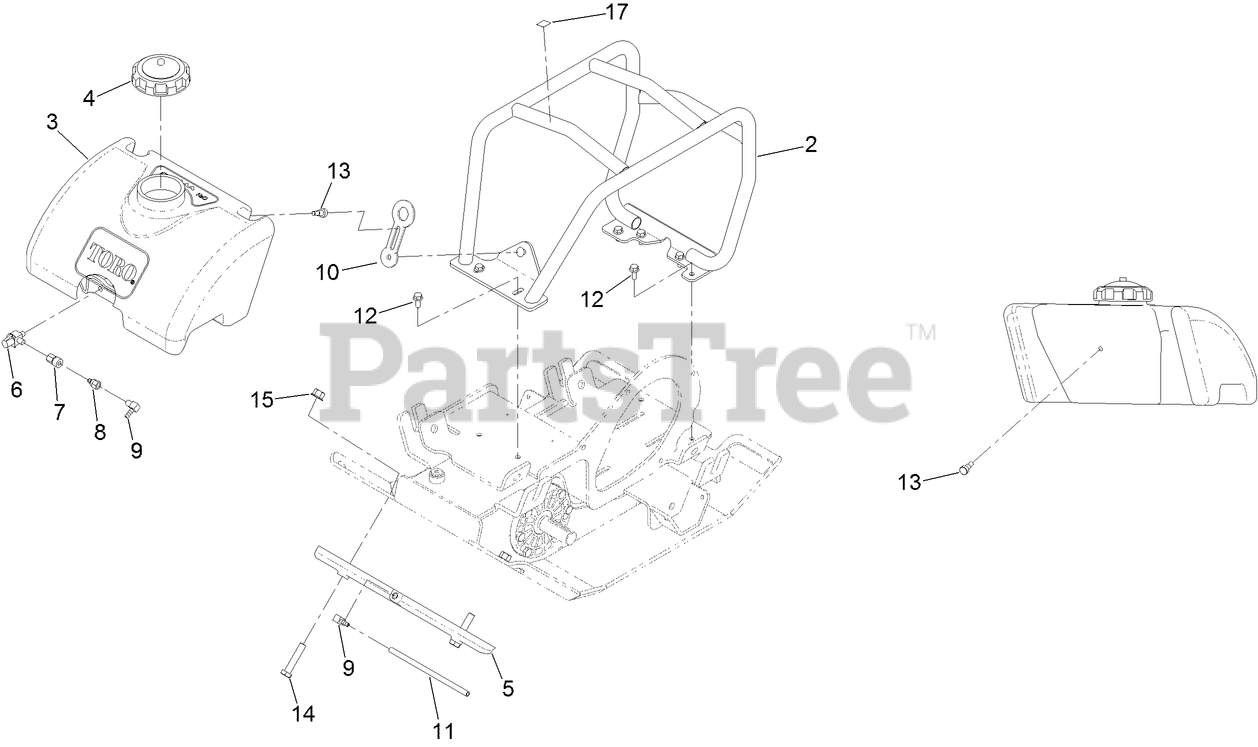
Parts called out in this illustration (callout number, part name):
2	CAGE-ROLL
3	TANK-WATER
4	CAP-PLASTIC
5	SPRINKLER
6	VALVE-BALL
7	FITTING-QUICK, FEMALE
8	FITTING-QUICK, FEMALE, NIPPLE
9	FITTING-HYD, 90 DEG
10	LATCH-RUBBER
11	HOSE-WATER
12	SCREW-HHF
13	SCREW-HSBH
14	SCREW-HH
15	NUT-LOCK, HHF
17	DECAL-POINT, LIFT
